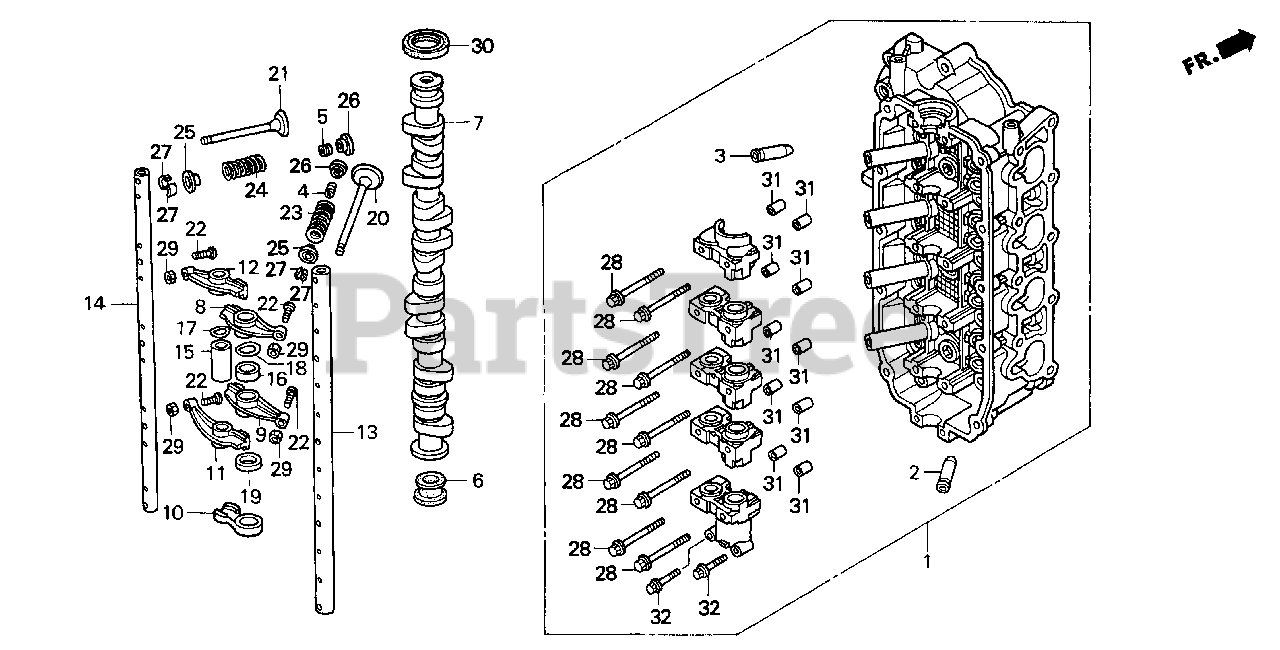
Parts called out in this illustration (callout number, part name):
1	CYLINDER HEAD SUB-ASSY. *NH8* (DARK GRAY)
2	GUIDE, VALVE (OVER SIZE)
3	GUIDE, EX. VALVE (OVER SIZE)
4	SEAL A, VALVE STEM (NOK)
5	SEAL B, VALVE STEM (NOK)
6	RUBBER, CYLINDER HEAD SEAL
8	ARM A, IN. ROCKER
9	ARM B, IN. ROCKER
10	ARM, FUEL PUMP ROCKER
11	ARM A, EX. ROCKER
12	ARM B, EX. ROCKER
13	SHAFT, IN. ROCKER ARM
14	SHAFT, EX. ROCKER ARM
15	COLLAR, ROCKER (A)
16	COLLAR, ROCKER (B)
17	WASHER, WAVE
18	WASHER, IN. WAVE
19	COLLAR A, IN. ROCKER
20	VALVE, IN. (TMSS)
21	VALVE, EX. (TMSS)
22	SCREW, TAPPET ADJUSTING
23	SPRING, IN. VALVE (ORANGE) (NHK SPRING)
24	SPRING, EX. VALVE (VIOLET) (NIPPON HATSUJO)
25	RETAINER, VALVE SPRING
26	SEAT, VALVE SPRING
27	COTTER, VALVE (FUJI VALVE)
28	BOLT, FLANGE (8X76)
29	NUT, TAPPET ADJUSTING
30	OIL SEAL (35X50X8) (NOK)
31	PIN, DOWEL (10X16)
32	BOLT, FLANGE (6X40)
